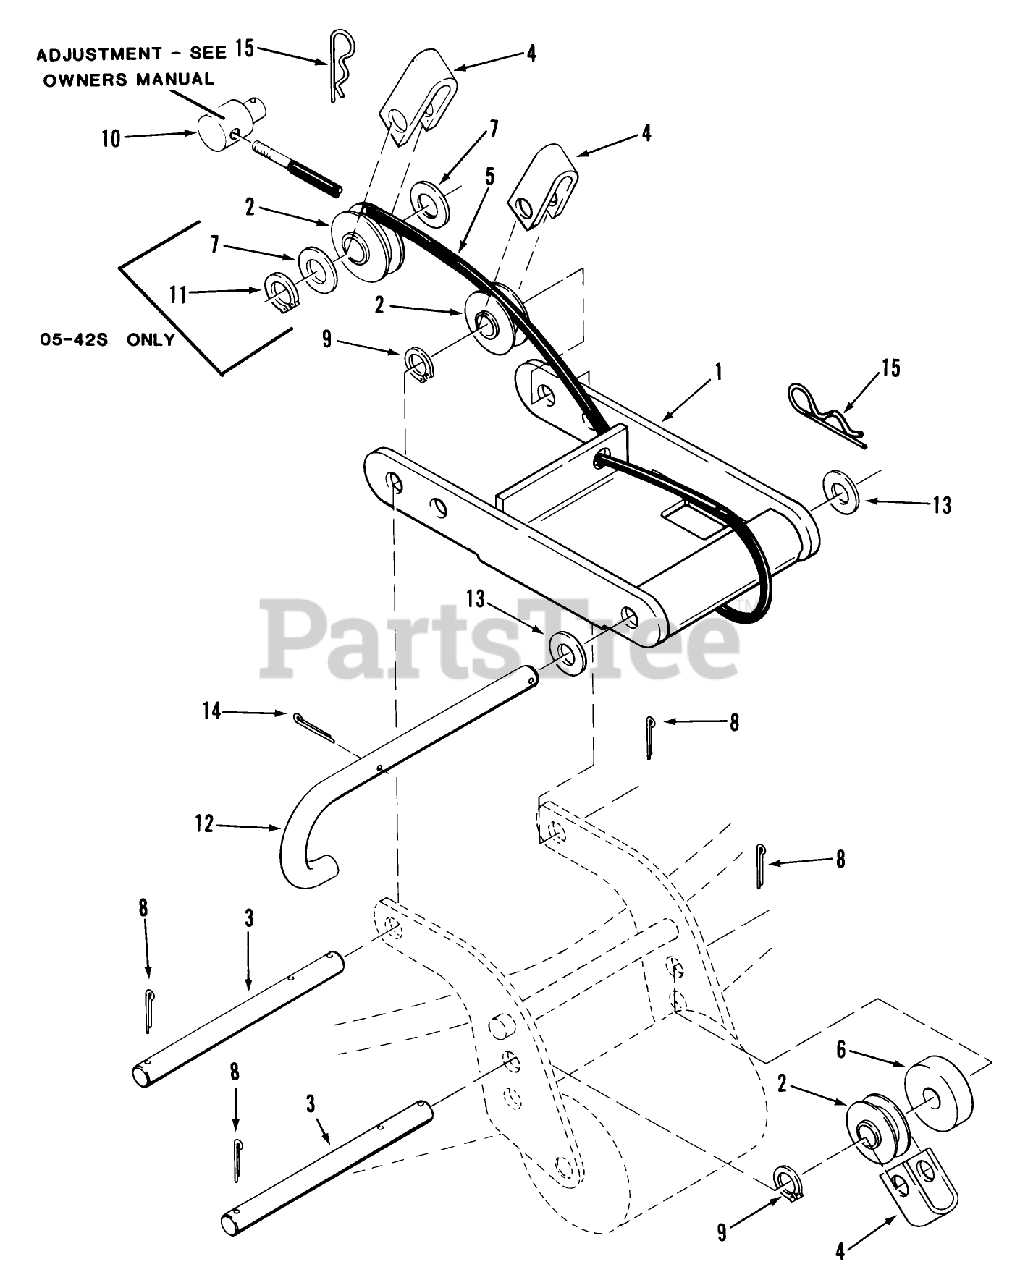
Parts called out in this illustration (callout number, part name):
1	Front Mount
1	ASSY-FRT MTG BRKT R
2	ROLLER-CABLE
3	ROD CABLE ROLLER
4	STRAP-CABLE
5	ASSY-CABLE
5	ASS'Y-CABLE
5	ASSY CABLE
6	SPACER
7	Washer
8	Pop Rivet
9	GRIP RING
10	TRUNNION
11	GRIP RING
13	Washer
15	Hairpin Cotter
